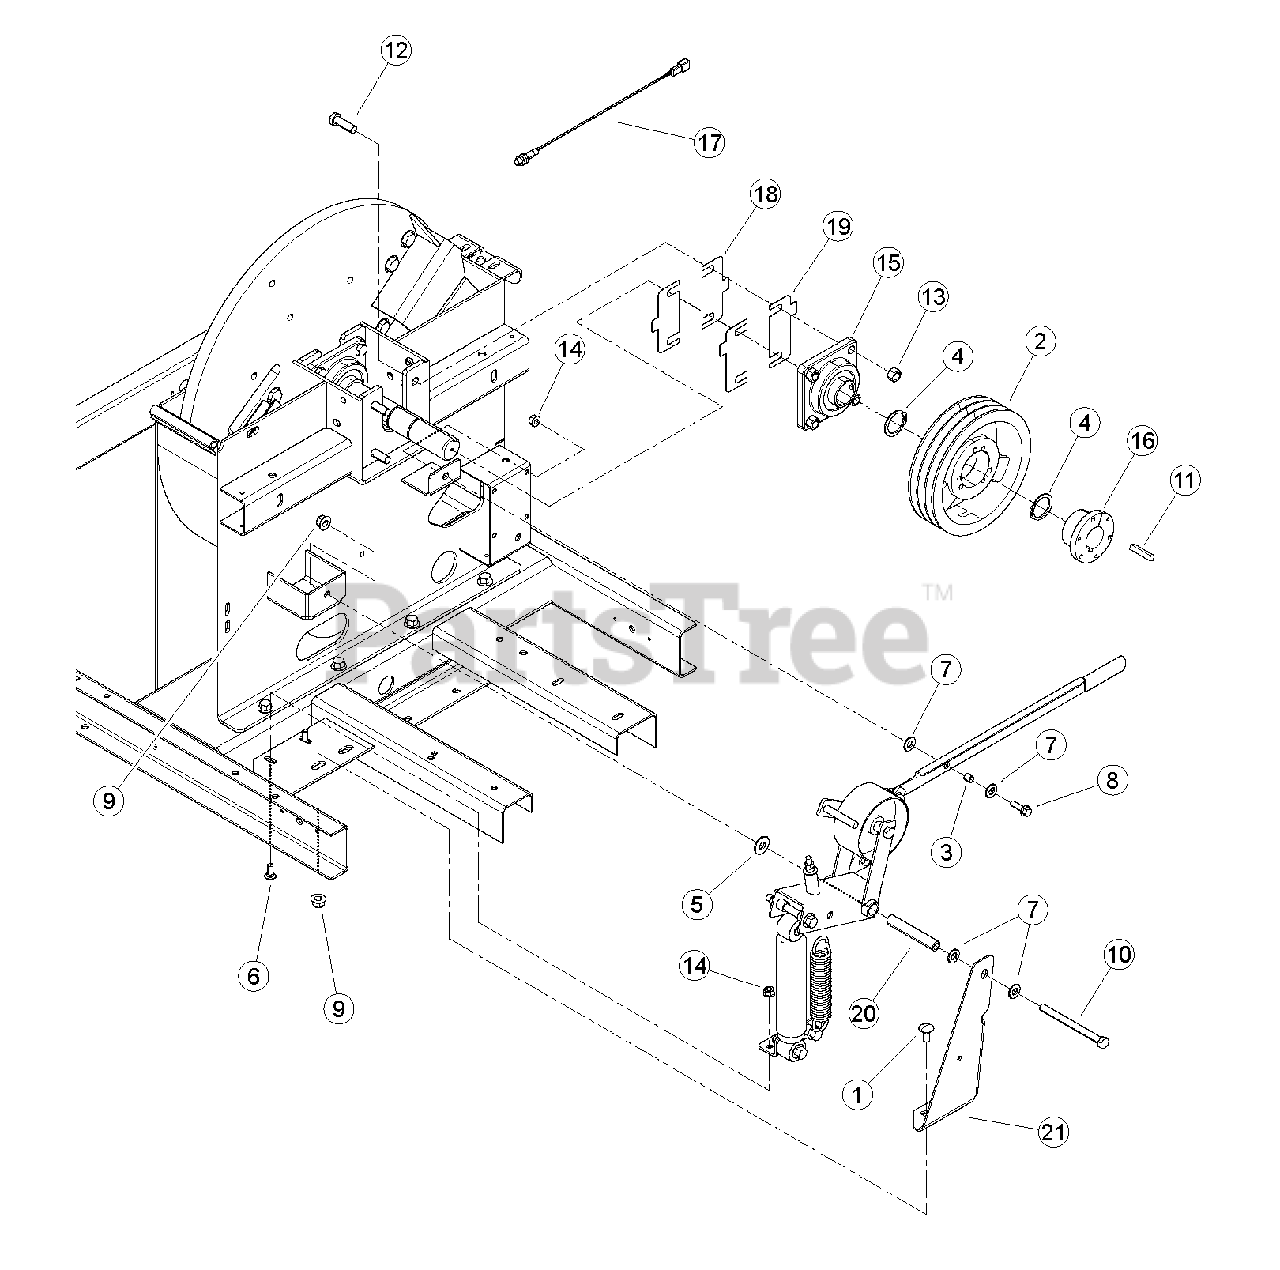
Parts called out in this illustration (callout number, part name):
1	BOLT, 1/2 X 1 CARRIAGE GR5 ZP
2	SHEAVE, 3BQ9.4, SK
3	BUSHING, 3/8 X 1/2 SLEEVE LUBE
4	RING, 1-3/4 EXT HEAVY DUTY SNAP
5	WASHER, 1/2" FLAT ZP
6	BOLT, 3/8 X 1" GR5 CRG NC ZP
7	WASHER, 1/2" SAE FLAT ZP
8	BOLT, 3/8 X 1-1/4 FLANGE NC
9	NUT, 1/2-13 NYLOCK FLANGE
10	BOLT 1/2 X 6 G5 HCS ZP
11	KEY, 3/8" SQ X 2" LG PLAIN
12	BOLT, 9/16 X 1-3/4 HEX GR5 ZP
13	NUT, 9/16 CENTER LOCK GRB ZP
14	NUT, 3/8-16 NYLOCK FLANGE
15	BEARING, 1-3/4 4 BOLT FLANGE
16	BUSHING, SK 1-3/4"
17	SENSOR, M12 PNP PROXIMITY (REPLACEMENT PART)
18	SHIM, 20 GA.
19	SHIM, 16 GA.
20	BUSHING, IDLER PIVOT
21	BRACE, IDLER
